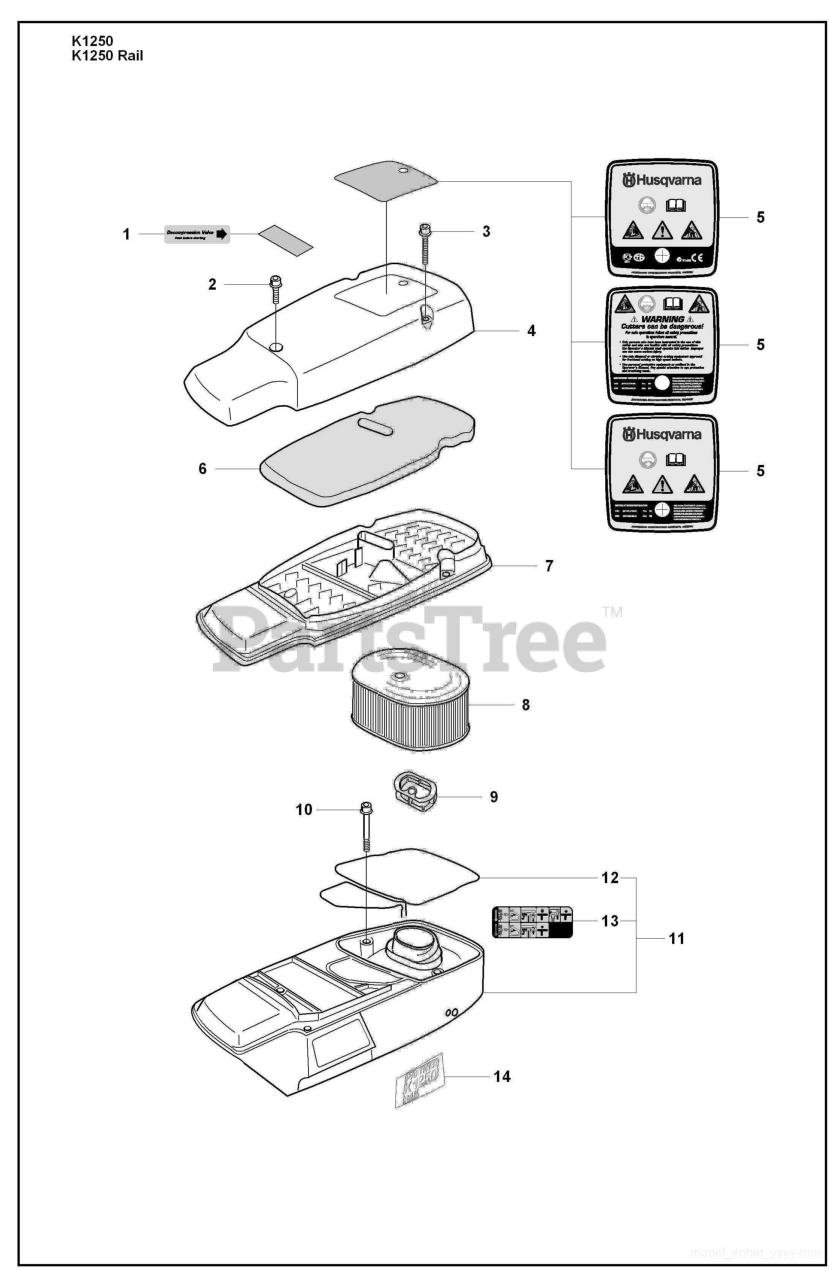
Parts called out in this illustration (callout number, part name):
2	SCREW
4	FILTER COVER
5	LABEL
7	FILTER BOTTOM
8	AIR FILTER
11	CYLINDER COVER
14	LABEL
